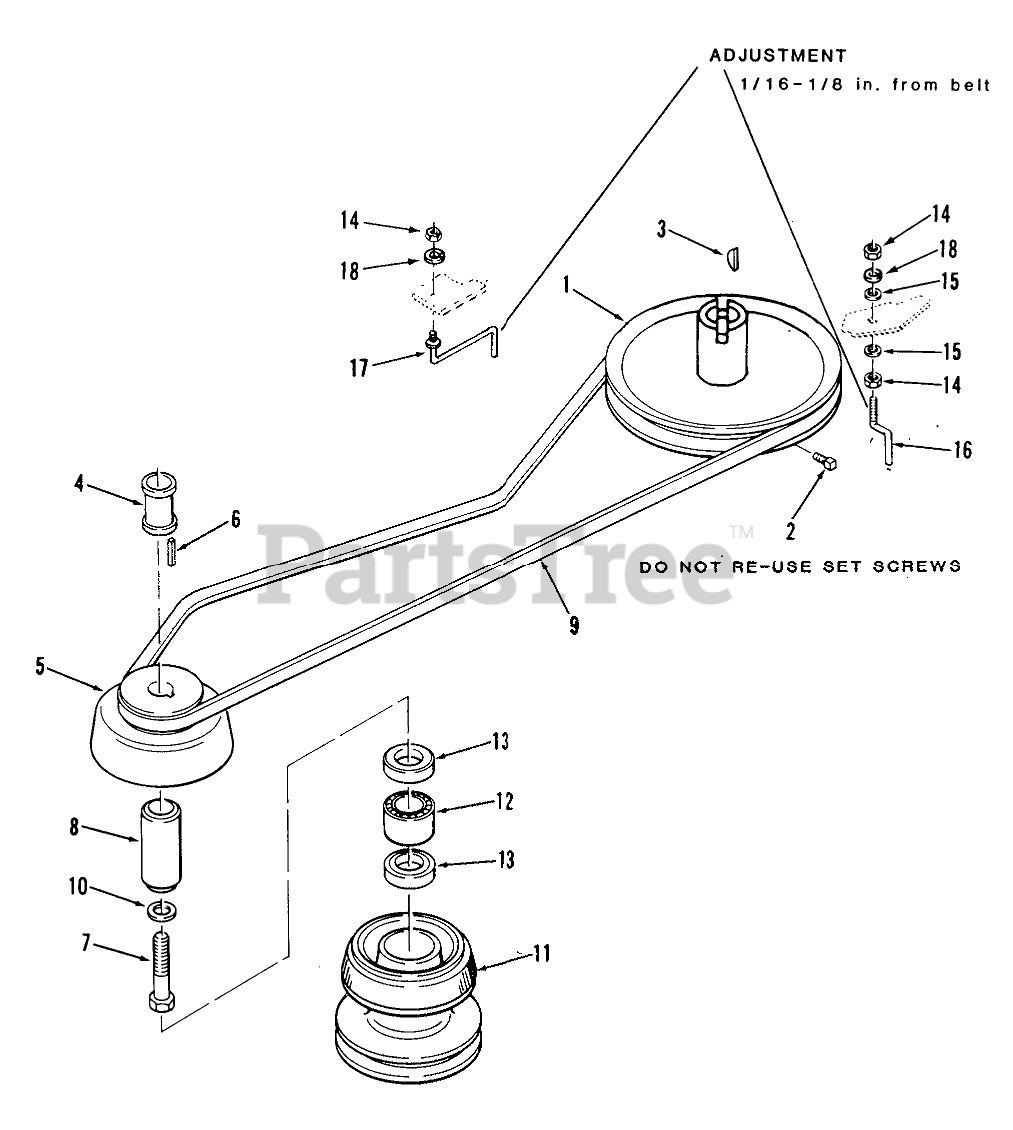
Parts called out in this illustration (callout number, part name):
1	PULLEY-TRANS (B)
2	Set Screw
3	KEY-HI-PRO
4	SPACER-TUBE
5	PULLEY-ENGINE
7	HEX HD CAP SCREW
8	RACE-BEARING
9	V-BELT
10	Special Washer 227-5
11	ASSY PULLEY MWR DR
12	BRG-NEEDLE OPEN END
13	SEAL-OIL
14	Nut
15	WASHER 5/16 SAE
16	GUIDE-BELT
17	GUIDE-BELT
18	Lockwasher
